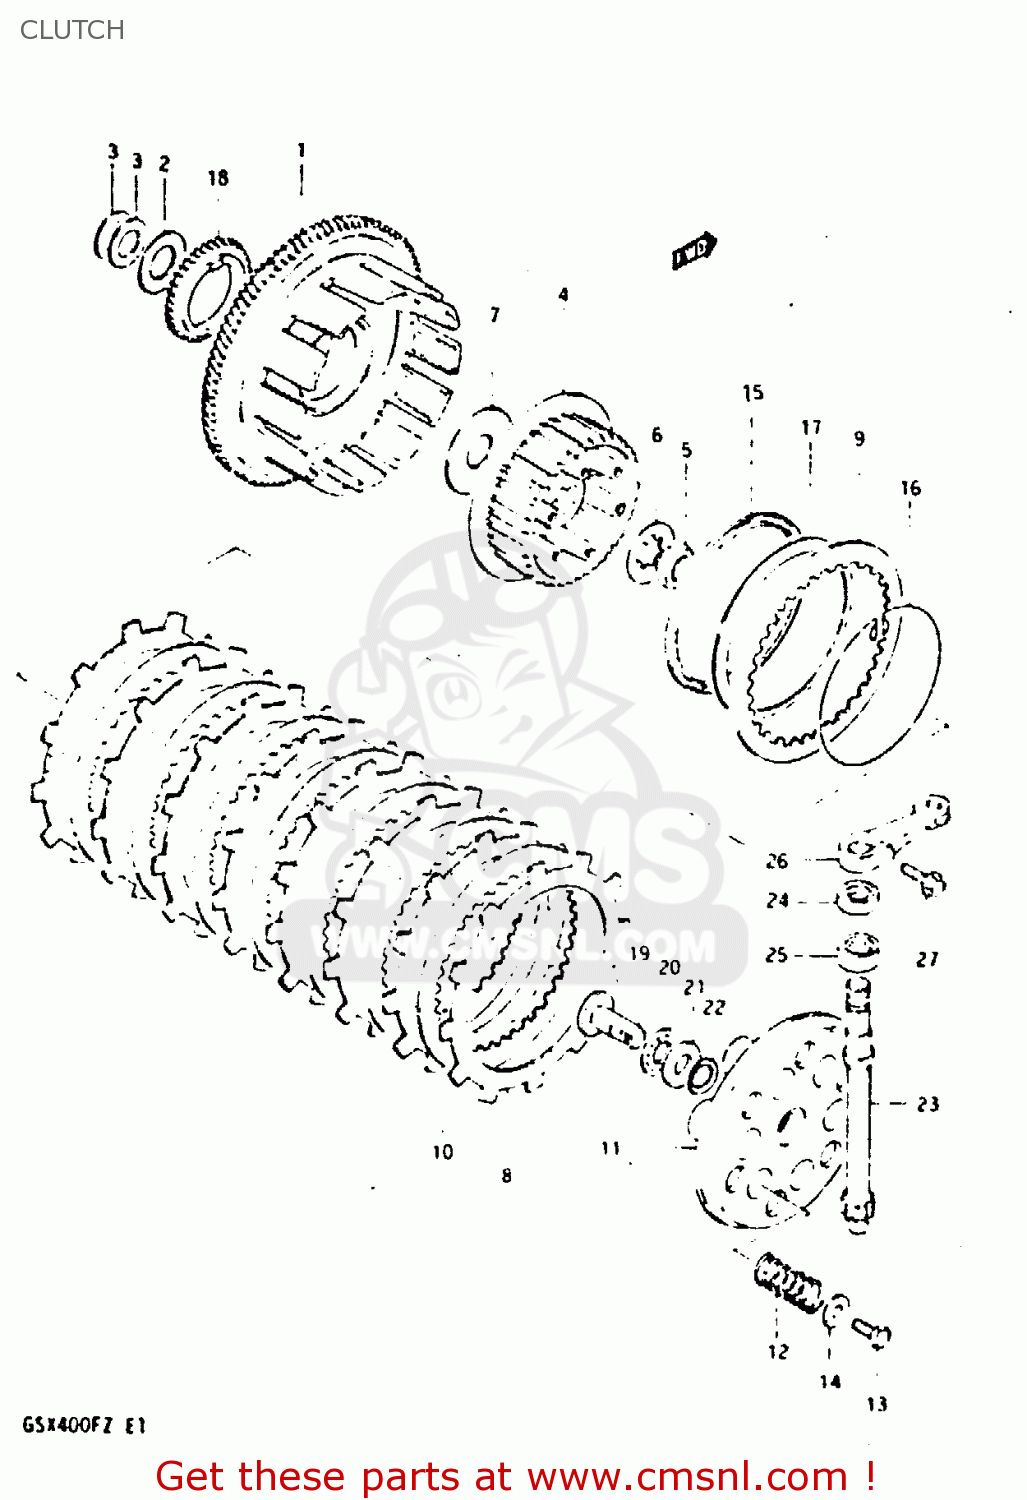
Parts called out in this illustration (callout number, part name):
1	GEAR SET, PRIMARY DRIVEN (NT:92)
2	WASHER
3	WASHER
4	HUB, SLEEVE
5	NUT
6	WASHER,LOCK
7	WASHER
8	PLATE,CLUTCH DRIVE (MCA)
9	PLATE,CLUTCH DRIVEN(T:2.0) (NAS)
10	PLATE,CLUTCH DRIVEN (NAS)
11	DISC, PRESSURE
12	SPRING
13	BOLT, UPPER
14	WASHER
15	SEAT,WAVE WASHER
16	RING,STOPPER
17	WASHER
18	GEAR, OIL PUMP DRIVE (NT:38)
19	RACK,CLUTCH RELEASE
20	BEARING(15X28X2)
21	WASHER
22	WASHER
23	PINION, RELEASE
24	OIL SEAL
25	BEARING(15X22X12)
26	ARM,CLUTCH RELEASE
27	BOLT,REAR
